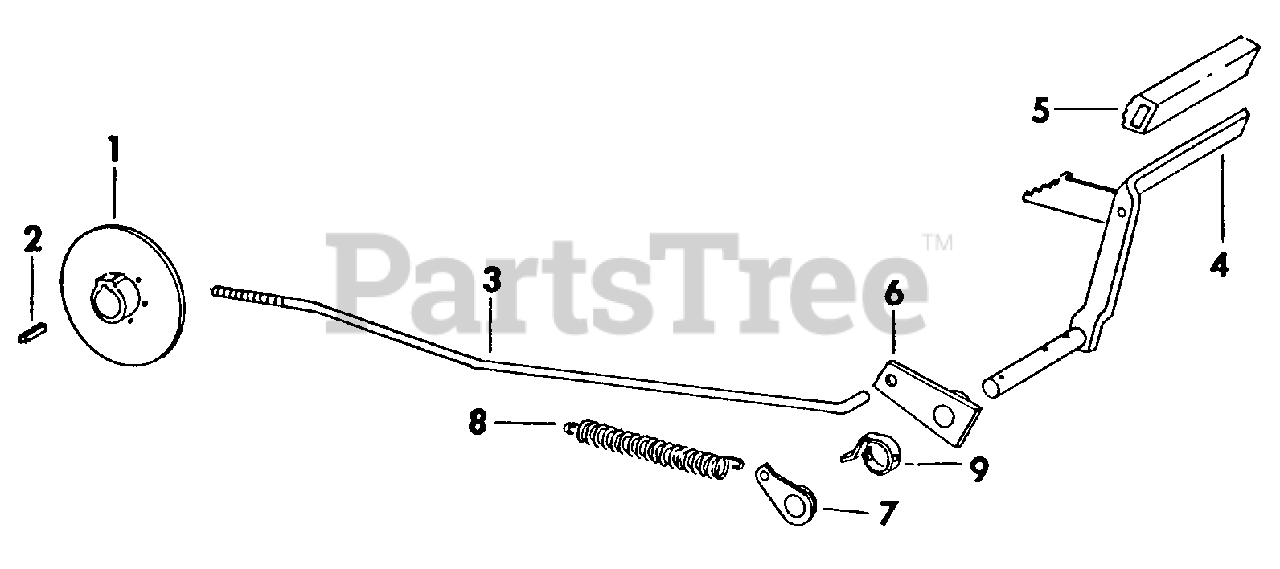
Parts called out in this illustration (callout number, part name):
1	Disc & Hub Assy
2	Key, 3/16 X 3/4 Woodruff No. 9
3	Rod, Brake
4	Pedal Assy, Clutch & Brake
5	Pedal, Foot
6	Lever Assy, Foot Pedal Brake
7	Brake Assy
8	Spring, Extension
9	Spring, Clutch
